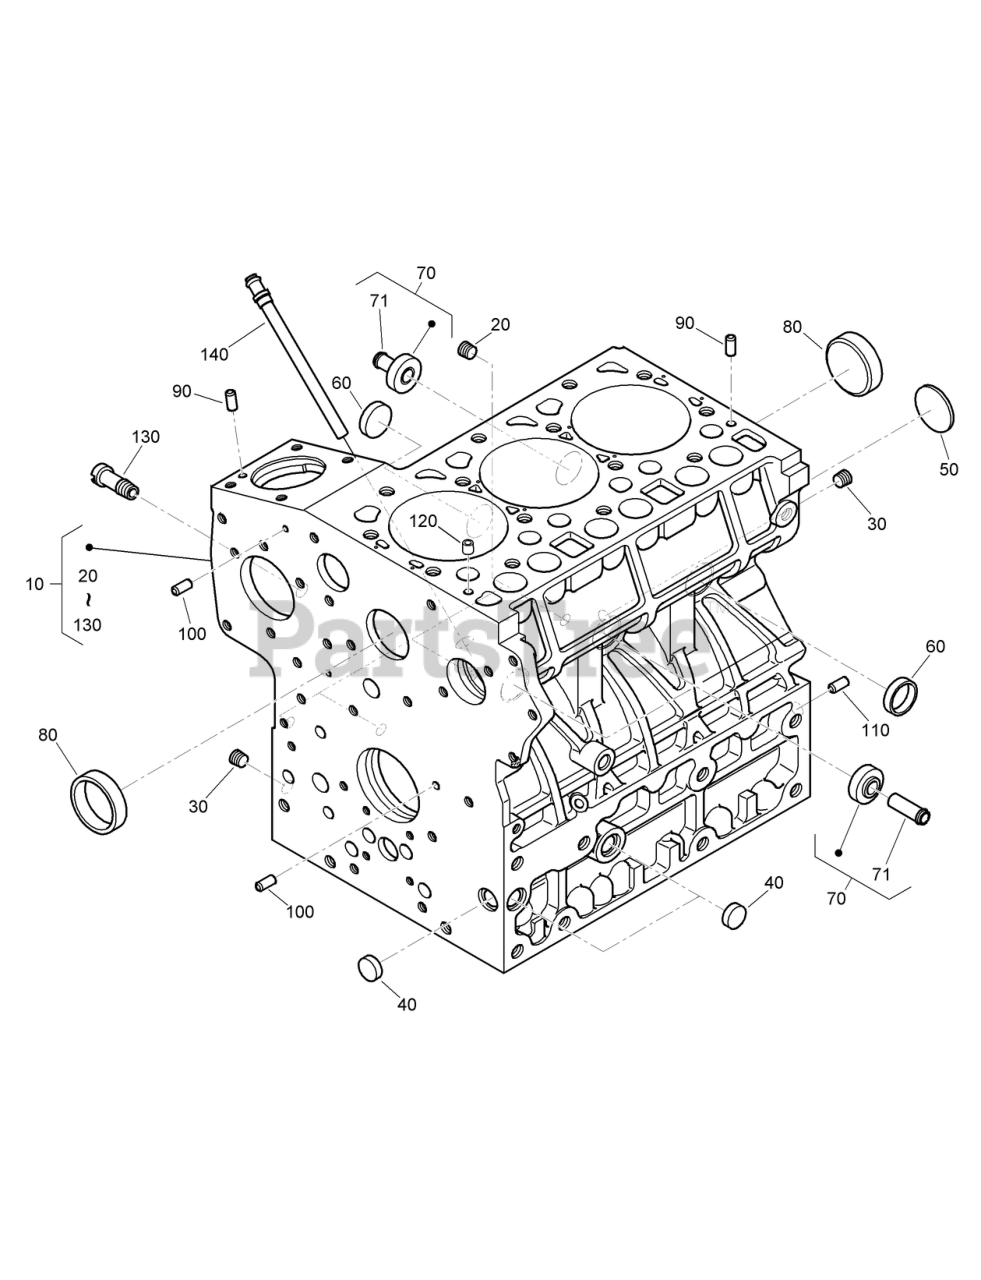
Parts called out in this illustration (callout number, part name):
10	CRANKCASE
50	PLUG-EXPANSION
60	CAP-SEALING
71	PIPE-RETURN, WATER
80	CAP-SEALING
90	PIN-STRAIGHT
100	PIN-STRAIGHT
110	PIN-STRAIGHT
120	PIN-PIPE
130	PIPE-RETURN, WATER
140	PIPE-RETURN, OIL
